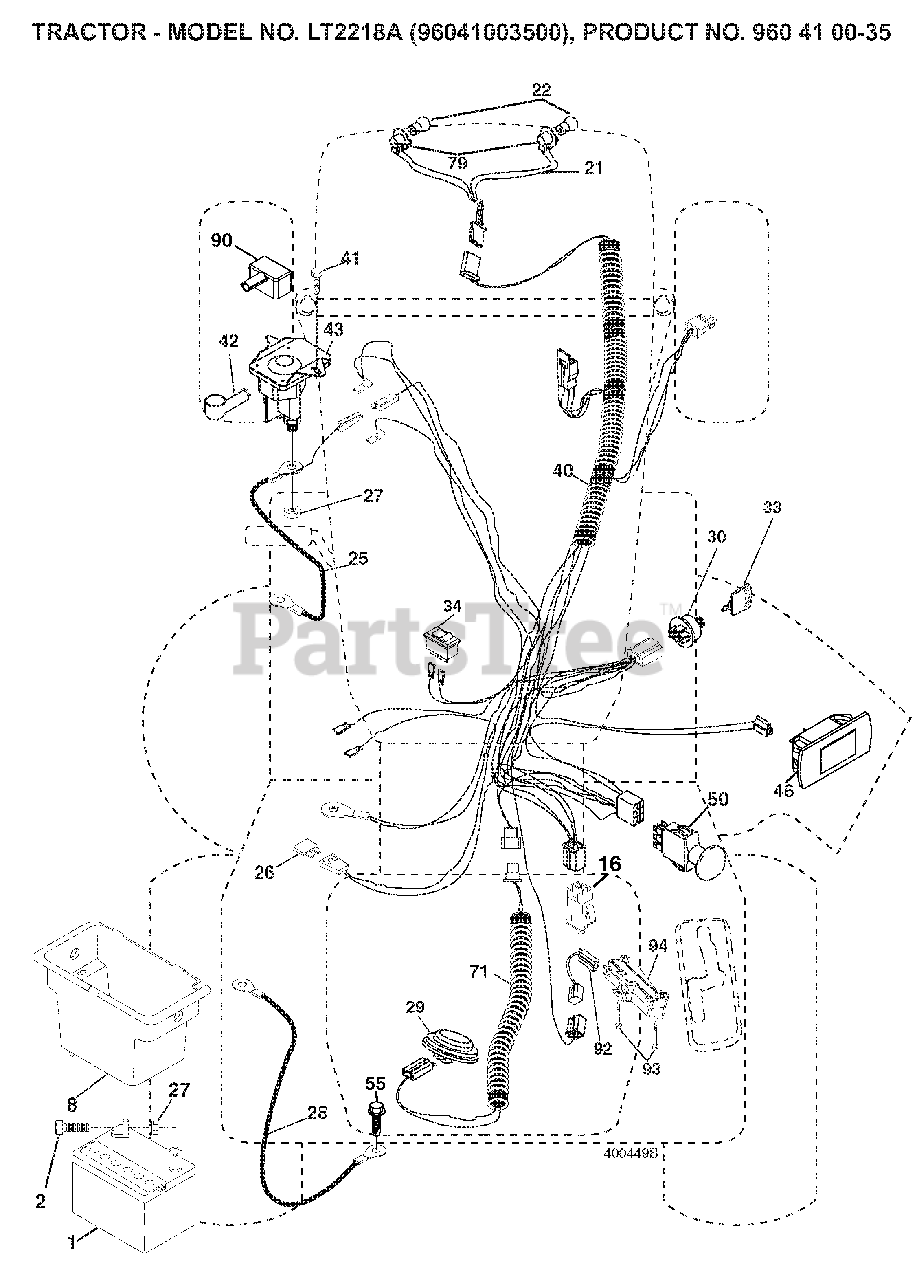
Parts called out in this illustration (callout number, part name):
1	REPL BY 532 12 38-99
8	BOX.BATTERY.MNT.REAR.L
16	SWITCH INTERLOOK PUSH-IN
21	HARNESS.W/LIGHT SOCKET
22	LIGHTBULB
25	CABLE.START.RED.17.5".
26	FUSE 20AMP
27	NUT
28	CABLE.BLACK.18"REAR.BA
29	SWITCH.SEAT.DELTA.OPC.
30	SWITCH.IGN.DELTA.W.LGH.ROS
33	KEY MLD GEN DELTA
34	SWITCH LT
40	HARNESS.IGN.DASH.HUQ/P
41	SCREW
42	TERMINAL COVER
43	SOLENOID.W/BRASS.PLUNG
46	GUAGE.SRVCMNDR.HRMTR.
50	PTO SWITCH
55	SCREW 5/16"
71	HARNESS.IGN.CHASS.TEX.REAR.BAT
79	BULB HOLDER ASM.
90	COVER, TERMINAL BATTERY
92	HARNESS.PIGTAIL.CONSLE
93	SCREW.PLASTITE
94	MODULE.REVERSE.ROS
